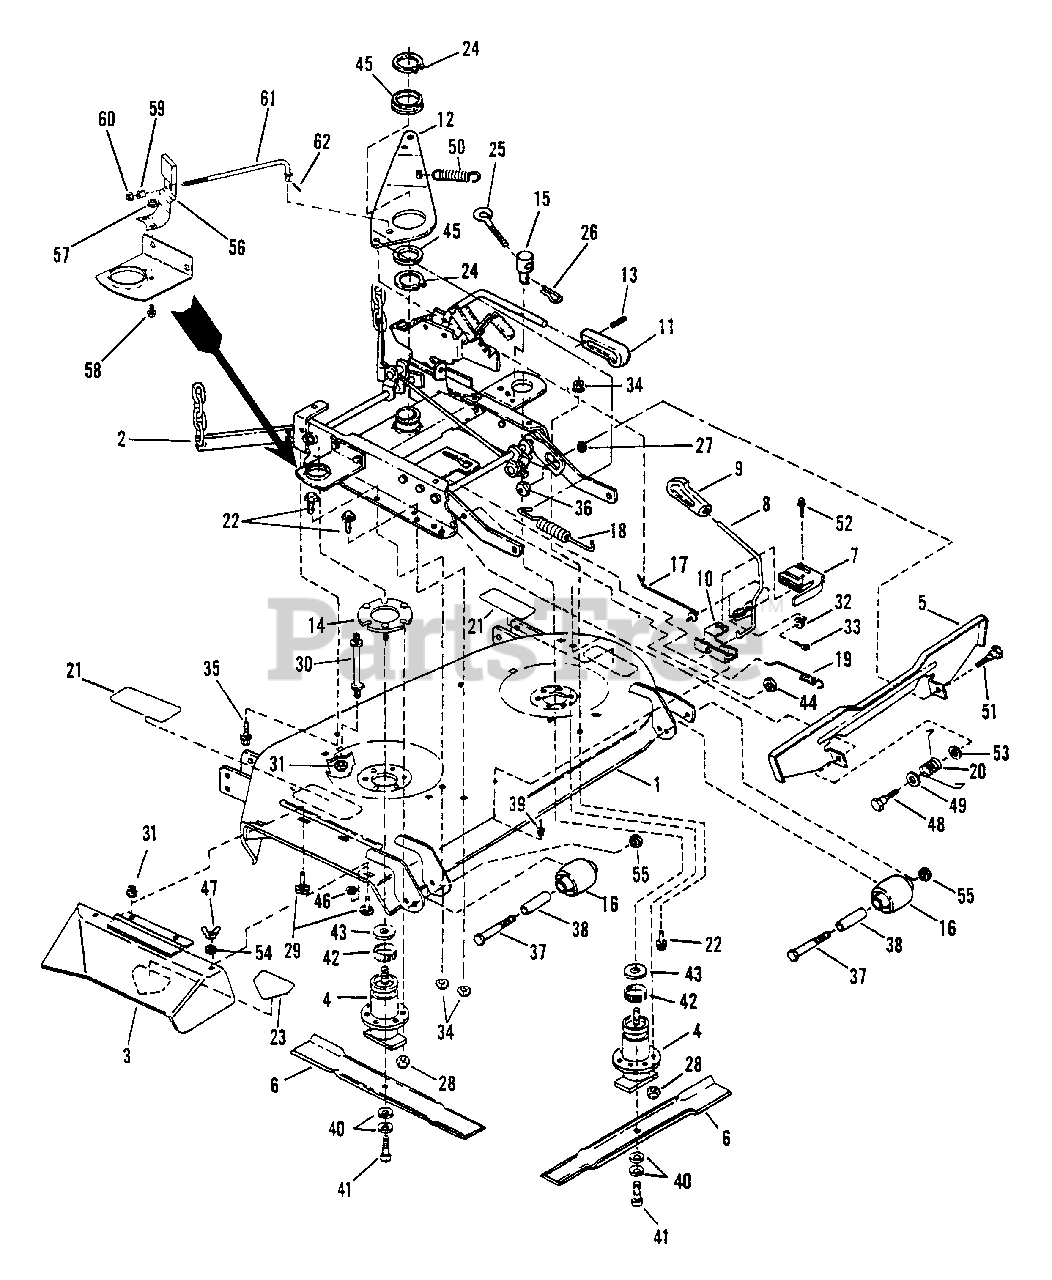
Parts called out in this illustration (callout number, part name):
1	ASSEMBLY, Deck
2	ASSEMBLY, Rail
3	ASSEMBLY, Side Chute
4	ASSEMBLY, Spindle
5	ASSEMBLY, Pedal
6	21" BLADE
7	SWITCH, Deck Interlock
8	LEVER, Blade Engagement
9	GRIP, Handle
10	MOUNT, Handle
11	GRIP, Height Adjustment Lever
12	ARM, Idler
13	PIN, 3/16 x 3/4" Roll
14	ASSEMBLY, Spindle Ring
15	SWIVEL, Adjustable
16	ROLLER
17	ROD, Idler
18	SPRING, Belt
19	SPRING, Latch
20	SPRING, Pedal
21	DECAL, Caution
22	BOLT, 5/16-18 x 5/8" Hex Flange Lock
23	DECAL, Danger
24	RING, 2" External Retaining
25	BOLT, 5/16-18 x 3" Eye
26	PIN, 3/32 x 1-1/2" Hair
27	WASHER, 3/8 Internal Tooth Lock
28	NUT, 3/8-16 Hex Lock
29	BOLT, 5/16-18 X 3/4" Yellow Zinc Carriage
30	STUD, 5/16-18 x 3-1/2"
31	NUT, 5/16-18 Hex Flange Lock
32	WASHER, 1/4 Flat
33	PIN, 3/32 x 3/4" Cotter
34	NUT, 5/16-18 Hex Flange Lock
35	SCREW, 5/16-18 x 5/8" Self-Tapping
36	ECCENTRIC, Leveling
37	SCREW, 3/8-24 x 3-3/4" Hex Head Cap
38	SPACER
39	SCREW, 1/4-20 x 5/8" Self-Tapping
40	WASHER, Cone
41	SCREW, 3/8-24 x 1" Hex Head Cap
42	RING, Tolerance
44	NUT, 3/8-24 Hex Lock
45	WASHER, 2" I.D. Nylon
46	RETAINER, 5/16 Bolt
47	NUT, 5/16-18 Wing Lock
48	BOLT, 3/8-24 x 9/16" Shoulder
49	WASHER, 1/2 Flat
50	SPRING, Return
51	BOLT, 3/8-24 x 3/4" Shoulder
52	SCREW, #10-32 x 1" Self-Tapping
53	WASHER, 3/8" Flat
54	WASHER, 5/16 Flat
55	NUT, 3/8-24 Hex Lock (Nyloc)
56	SPRING BRAKE PAD
57	NUT, Flange Lock 1/4-20
58	BOLT, Flange Lock 1/4-20 x 1/2
59	BUSHING, 3/8" Snap Plastic
60	NUT, 1/4" Hex Nylock
61	LINK, Spindle Brake
62	PIN, 1/16 x 1/2" Cotter
